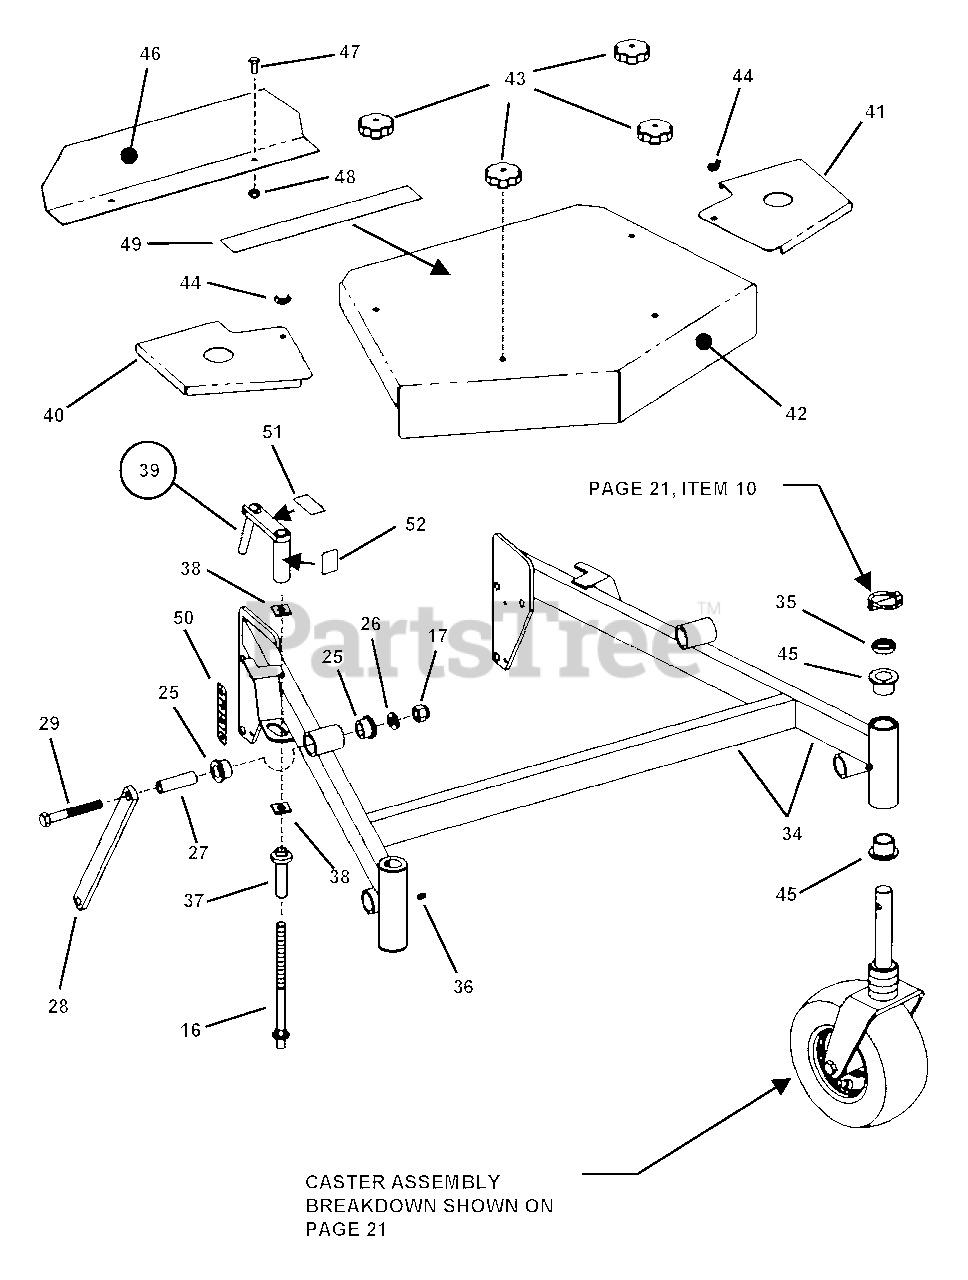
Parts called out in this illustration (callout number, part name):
16	STUD, Lift, 1/2-13 thread (both ends)
17	NUT, 1/2-13 Hex Nyloc
25	BUSHING, Suspension
26	WASHER, 1/2" Flat
27	SLEEVE, Suspension (All Models)
28	ARM, Suspension 12" Long (48" & 52" Decks)
29	BOLT, 1/2-13 x 3-3/4", Grade 5
34	WELDMENT, 48" Deck Frame
35	SPACER, 1" x 1 3/8 x .30" (PM)
36	FITTING, Lube 1/4-28
37	LIFT WASHER (Weldment)
38	WASHER, Lift
39	ASSEMBLY, Crank
40	COVER, 48" Right
41	COVER, 48" Left
42	COVER, 48" Center
43	KNOB, Hood
44	WING NUT, 5/16-18
45	BUSHING
46	SHIELD, Muffler (SPA610, SPA611)
47	BOLT, 5/16-18 X 3/4 GD5
48	NUT, 5/16-18 HEX NYLON LOCK
49	DECAL, Snapper Pro
50	DECAL, Height -of-Cut
51	DECAL, Caution Handle May Be Hot
52	DECAL, Oil Threads Here
